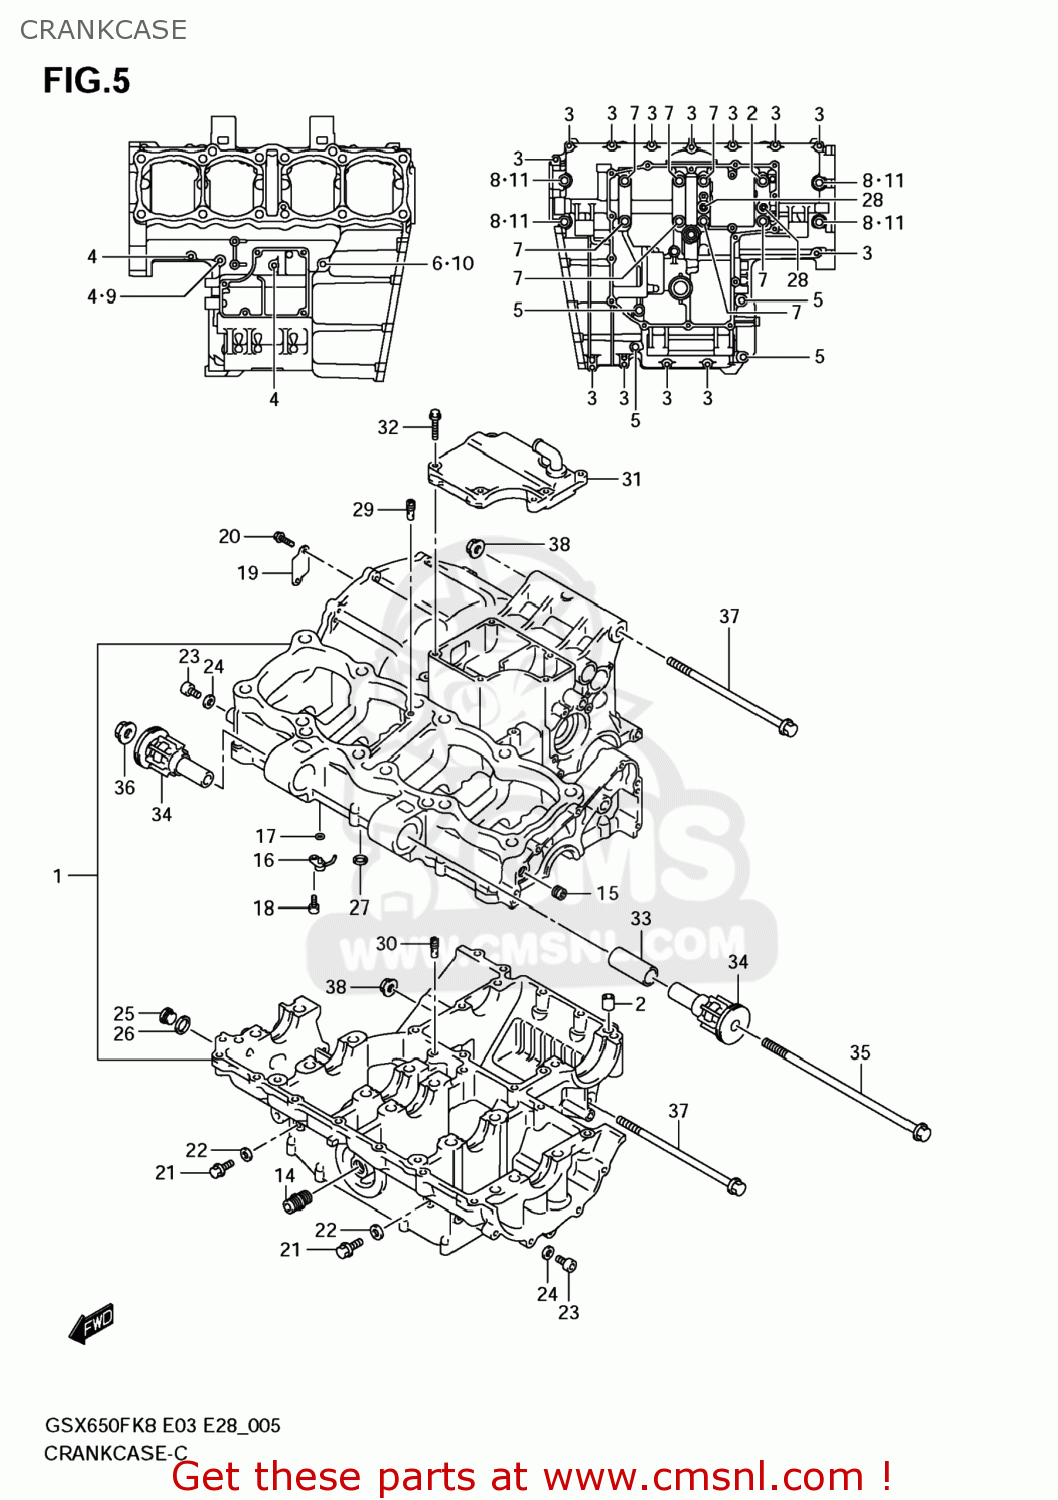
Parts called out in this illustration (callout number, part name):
1	CRANKCASE SET
2	PIN,CRANKCASE
3	BOLT
4	BOLT
5	BOLT
6	BOLT
7	BOLT(9X135)
8	BOLT(9X95)
9	GASKET(5.8X13X1.2) (NAS)
10	GASKET(8.2X14X1) (NAS)
11	GASKET(10.2X20X2).3 (NAS)
12	BEARING,CRANK THRUST(GREEN)
13	BEARING,CRANK THRUST(RED)
14	UNION,OIL STAND
15	JET,OIL GALLERY(3.6)
16	JET,PISTON COOLING
17	O RING(D:1.2,ID:4)
18	BOLT(6X12)
19	PLATE,OIL SEPARATOR
20	BOLT
21	BOLT
22	GASKET(6.2X13X1.2) (NAS)
23	BOLT
24	GASKET(8.2X14X1) (NAS)
25	PLUG,16X8
26	GASKET(16X22X2) (NAS)
27	O RING(D:1.9,ID:7.8)
28	O RING(D:1.9,ID:12.6)
29	JET(140)
30	JET,AIR(180)
31	COVER,BREATHER
32	BOLT(6X30)
33	SPACER,ENG MTG
34	BUSH,ENGINE MOUNTING
35	BOLT 10X215
36	NUT
37	BOLT(12X155)
38	NUT
